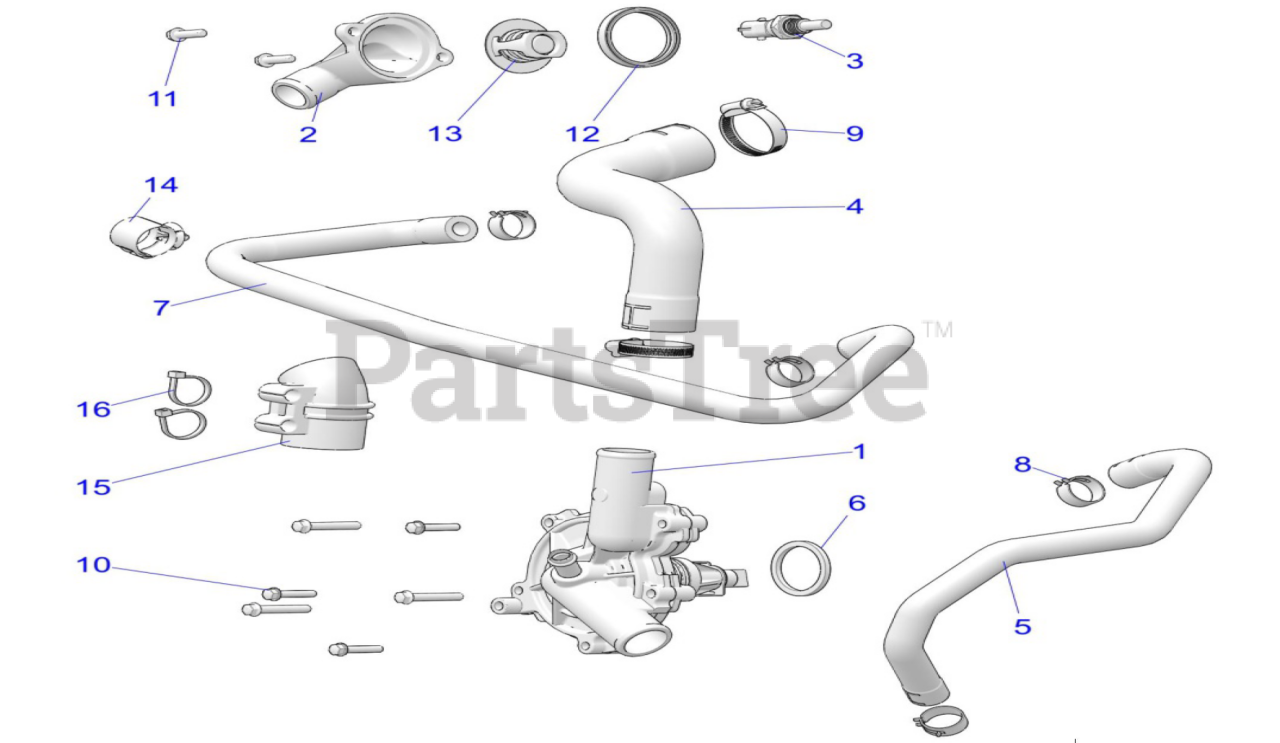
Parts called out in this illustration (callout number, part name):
1	ASM, WATERPUMP
2	SEAL-THERMOSTAT
3	SENSOR-THERMISTER
4	HOSE-WATERPUMP,OUT
5	HOSE-OIL COOLER OUT
6	FILTER, WP
7	HOSE-BYPASS LINE
8	CLAMP, HOSE, SPRING
9	CLAMP-HOSE(WORM DR)25-40MM
10	SCR-HXFL,M6X1.0X35,W/PATCHLOK
11	SCR-M6X20,HXFLG,0600214
12	COVER-THERMOSTAT
13	THERMOSTAT-44M FLANGE,180F
14	CLIP-HOSE
15	SUPPORT-STATOR WIRE
16	CABLE TIE (10)
